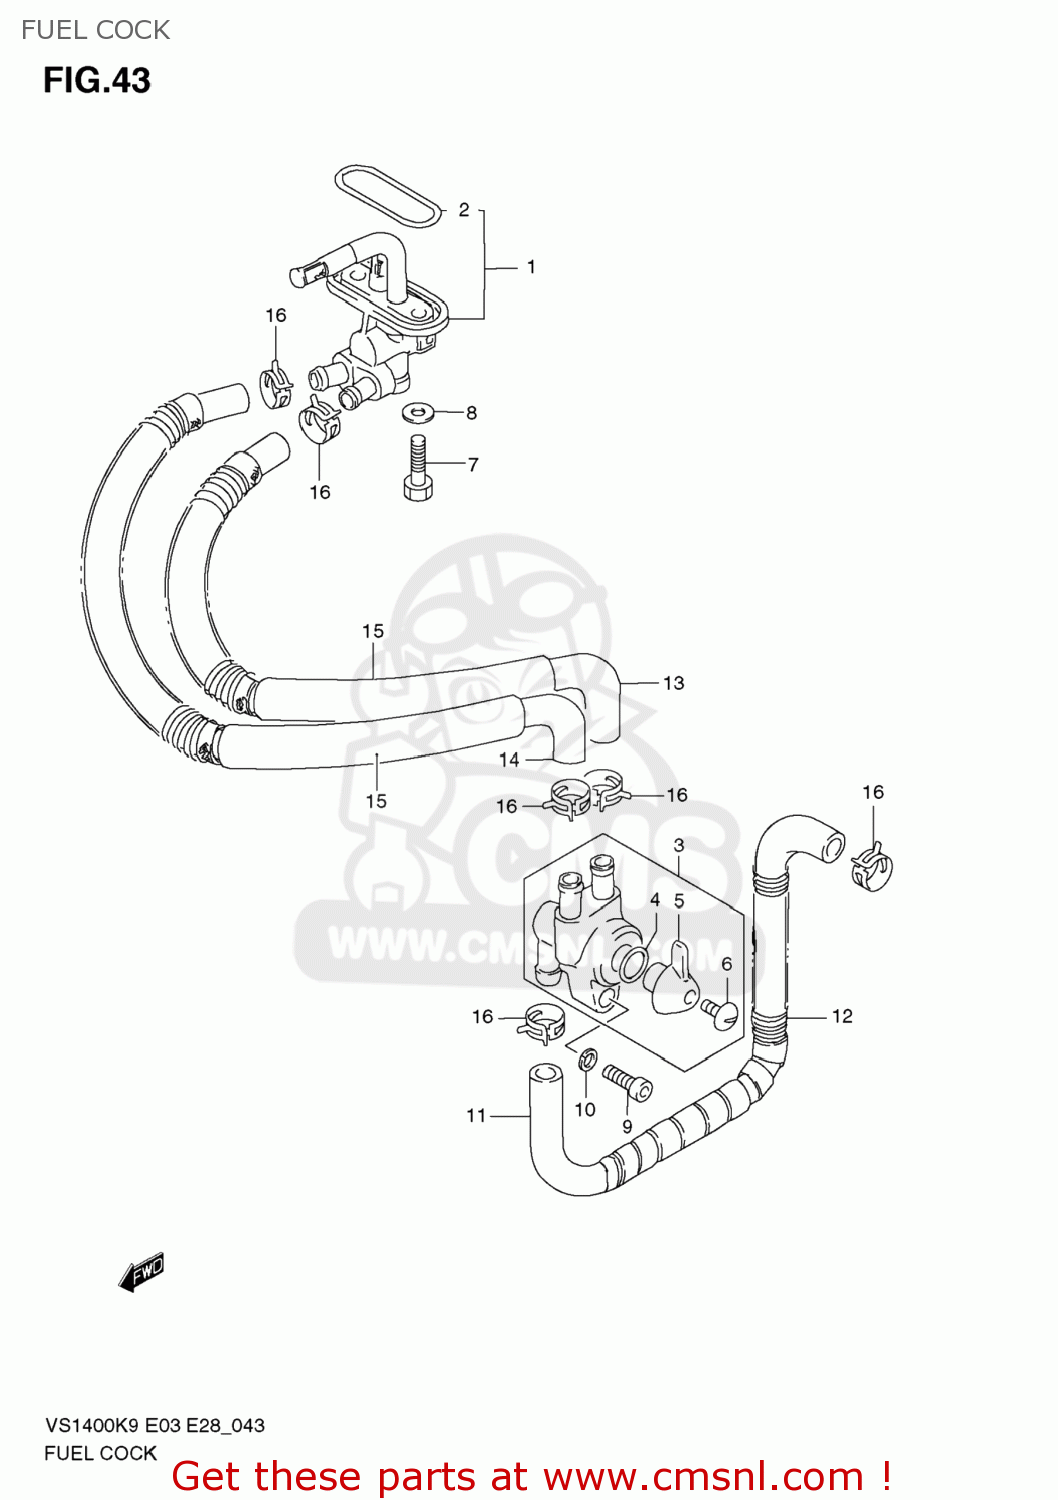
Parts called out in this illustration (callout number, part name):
1	COCK ASSY,FUEL
2	O RING,FUEL COCK
3	COCK ASSY,FUEL
4	O RING,LEVER
5	LEVER,FUEL COCK
6	SCREW,COCK LEVER
7	BOLT(6X20)
8	GASKET(6.4X11.5X0.8) (NAS)
9	BOLT
10	WASHER,LOCK
11	HOSE,FUEL PUMP & COCK
12	SPRING
13	HOSE,FUEL NO.1
14	HOSE,FUEL NO.2
15	TUBE,FUEL HOSE
16	CLIP
